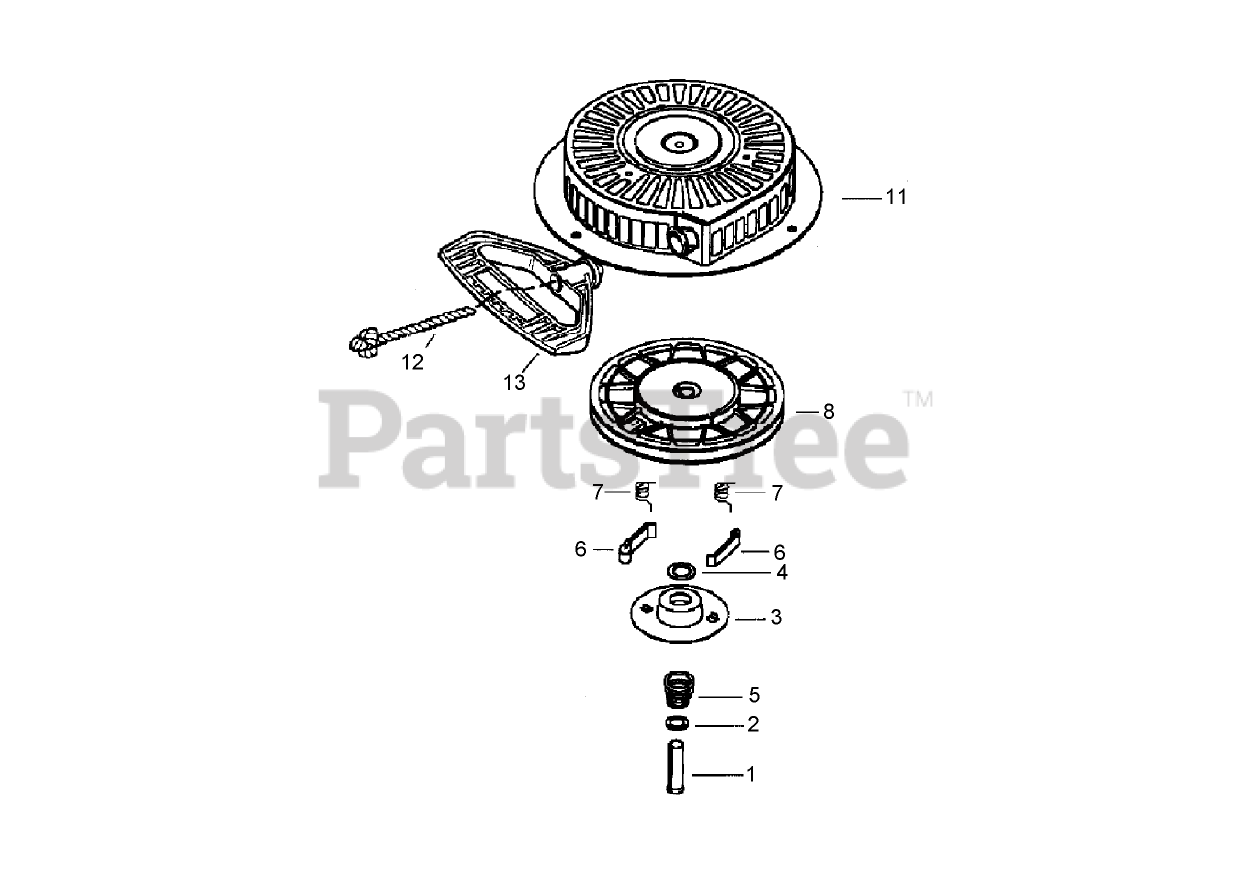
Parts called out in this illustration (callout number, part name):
1	Pin, Spring (Incl. Ref. #7)
2	Washer
3	Retainer
4	Washer
5	Spring-Brake
6	Dog-Starter
7	Spring-Dog
8	Pulley and Rewind Spring ASM
11	Starter Housing ASM
12	Rope-Starter (98 cut to length)
13	Handle-Starter, Mitten Grip
